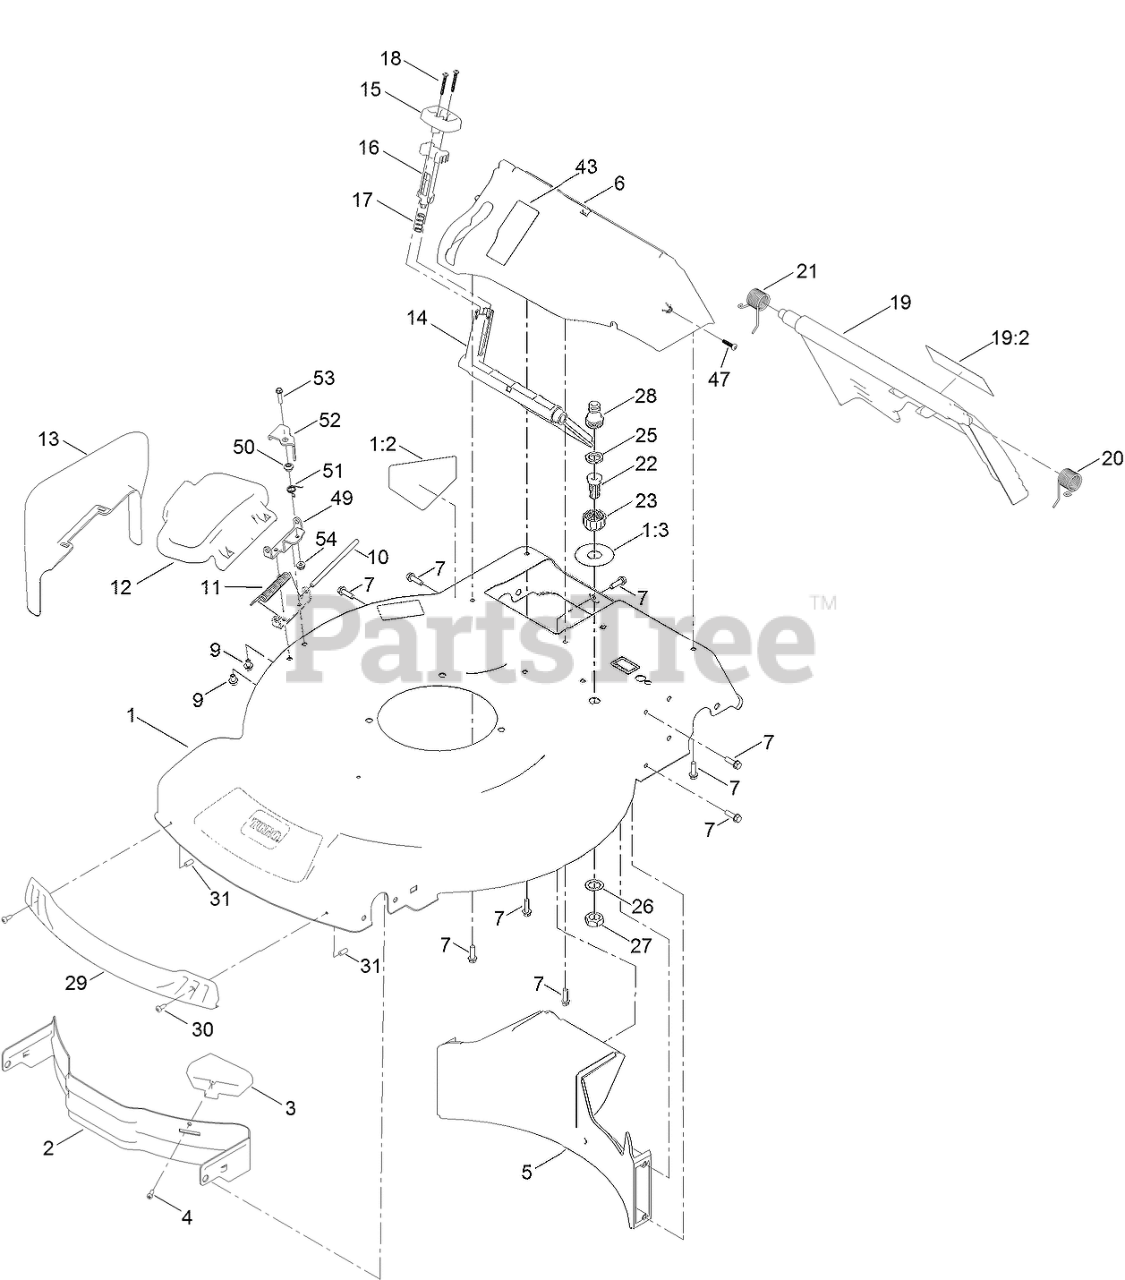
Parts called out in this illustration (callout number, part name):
1	HOUSING ASM
1:2	DECAL-DANGER
1:3	DECAL-QUICK WASH
2	BAFFLE-FRONT
3	KICKER-FRONT
4	SCREW-PPH
5	BAFFLE-REAR
6	CHUTE-RECYCLE
7	SCREW-HWH
9	SCREW-HWH
11	SPRING-TORSION
12	DEFLECTOR-DISCHARGE, SIDE
13	CHUTE-DISCHARGE, SIDE
14	DEFLECTOR-RECYCLE
15	KNOB-RECYCLE
16	LATCH-RECYCLE
17	SPRING-COMPRESSION
18	SCREW-PPH
19	REAR DOOR ASM
19:2	DECAL-WARNING
20	SPRING-TORSION
21	SPRING-TORSION
22	PORT-WASHOUT
23	COUPLING-HOSE, WASHOUT PORT
25	WASHER-SEAL, WASHOUT PORT
26	WASHER-LOCK
27	NUT-JAM
28	ADAPTER-CONNECT, QUICK
29	BUMPER
30	SCREW-FORMING, THREAD
31	CAP-PLUG
47	SCREW-PLASTITE
49	BRACKET-LOCKOUT
50	SPACER
51	SPRING-TORSION
52	LEVER-LOCKOUT
53	SCREW-HWH
54	NUT-LOCK, FLANGE
